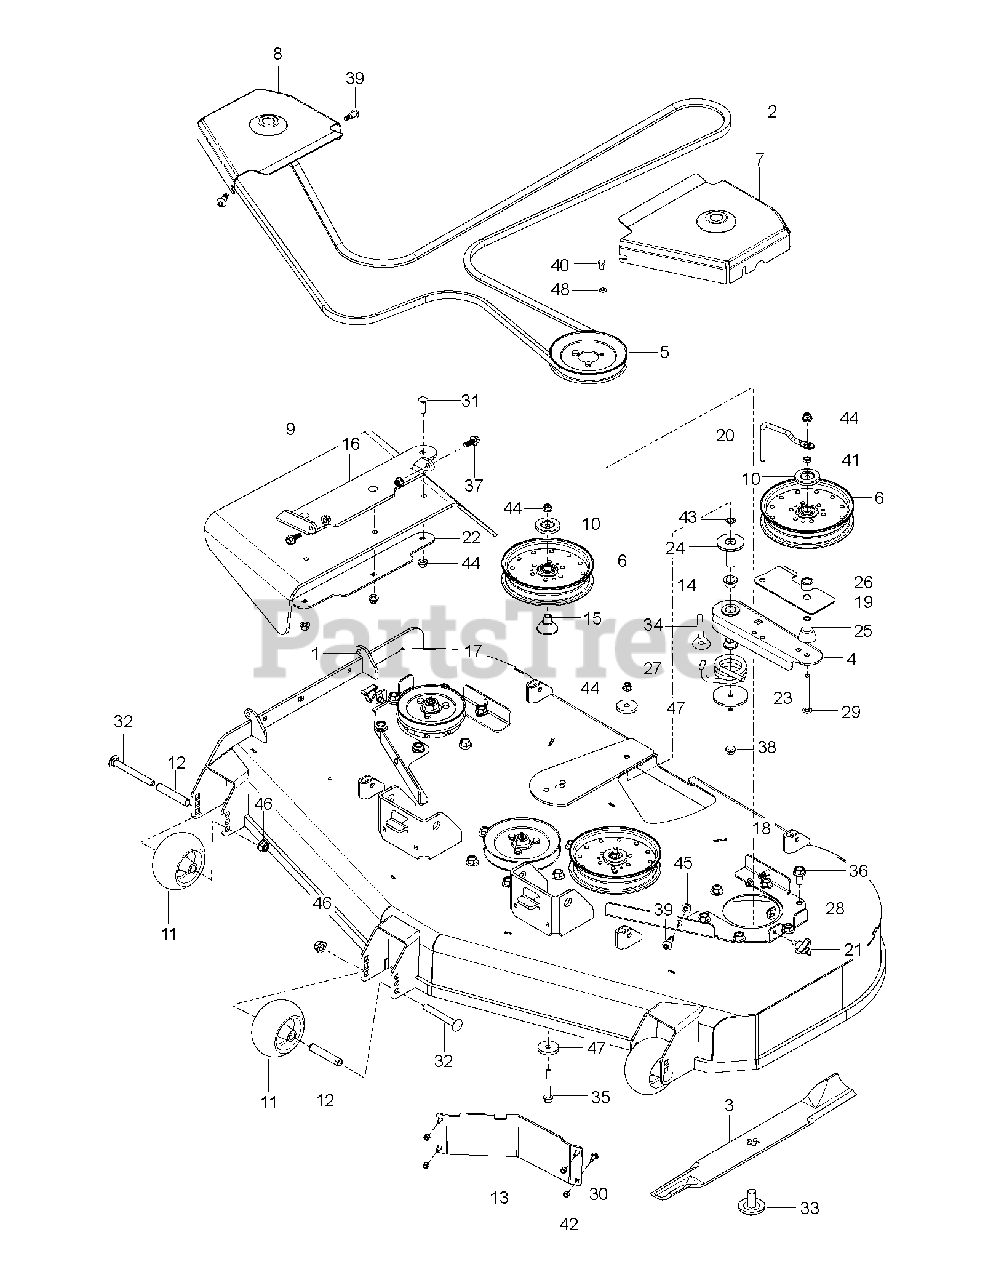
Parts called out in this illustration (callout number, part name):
1	DECK.SVC.W/DECALS.60".10GA.ORG
2	BELT 5V 176.00
3	BLADE, 21"
4	ARM.PNT.WLD.TENSIONR.IDLER.BLK
5	PULLEY - 6.57
6	PULLEY - IDLER 7"
7	COVER.PULLEY.LH.PNT
8	COVER.PULLEY.RH.PNT
9	Discharge Chute
10	DUST SHIELD
11	ROLLER, GAUGE .635 BORN
12	TUBE, ROLLER AXLE
13	BAFFLE, DIVERTER 54"/60" LH
14	BEARING, FLANGE
15	BEARING, IDLER ARM
16	BRACKET.CHUTE.ORG
17	BRACKET.PULLEY.COVER.LH.PNT
18	BRACKET.PULLEY.COVER.RH.PNT
19	Lower Guard Plate Belt, Pnt 431
20	KEEPER KEEPER., BELT
21	KNOB W/STUD
22	PLATE.BACKING.DISCHARGE.CHT.BK
23	PLATE.SPRING.RETAINER
24	SHAFT.MOUNT.ARM.IDLER
25	Idler Spacer
26	Pulley Intermediate Spacer
27	SPRING.TORSION.DECK.IDLER.TMSN
28	U-CLIP 5/16-18 NUT RETAINER
29	BOLT.RDHD SQNK 3/8-16 X 3-1/2
30	1/4-20X3/4 CARR BLT
31	BOLT.3/8-14X1.25
32	RHSNB 1/2-13 X 4.75 GR5 ZD
33	BLADE BOLT/WASHER
34	EYE BOLT, 3/8 X 4"
35	HHFS 3/8-16 X 2-3/4 GR5 ZD
36	HHFS 1/2-13 X 1 GR5 ZD
37	HHFS 3/8-16 X 1 GRD 5 ZD
38	HHFS 3/8-16 X 4 GR5 ZD
39	SCREW.SHLDR.3/8 X 1/2.5/16-18
40	HCS 5/16-18 X 1/2 GR 5 ZD
41	NUT 3/8-16 HEX JAM
42	RP_NUT 1/4-20 NYLOC
43	NUT 3/8 PALNUT RTNG BLK PHOS
44	NUT 3/8-16 HEX FLG NYLOC ZD
45	5/16-18 NYLOC FLANGE NUT
46	NUT, 1/2-13 HEX FLG NYLOC ZD
47	SPINDLE WASHER
48	WASH 5/16 DISC SPRING ZD
